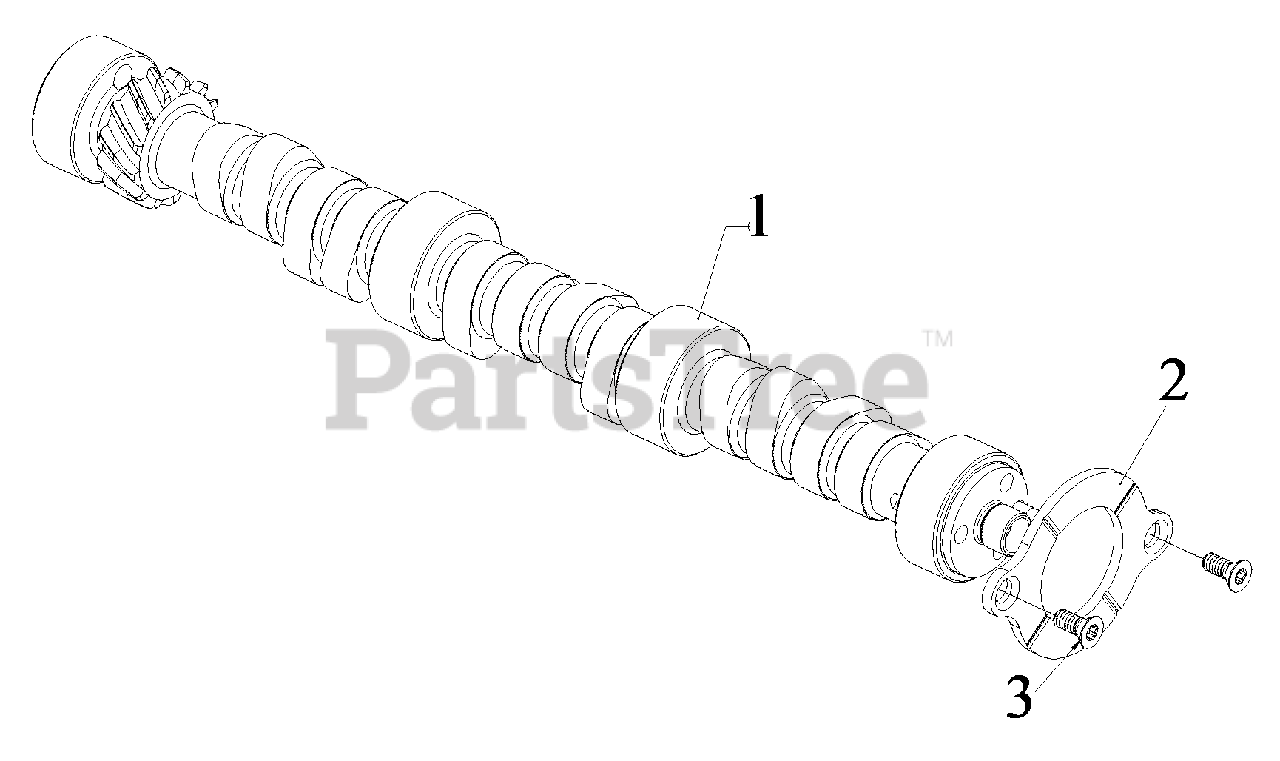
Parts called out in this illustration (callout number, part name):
1	CAMSHAFT
2	RETAINER, CAMSHAFT
3	BOLT, CAMSHAFT RETAINER
